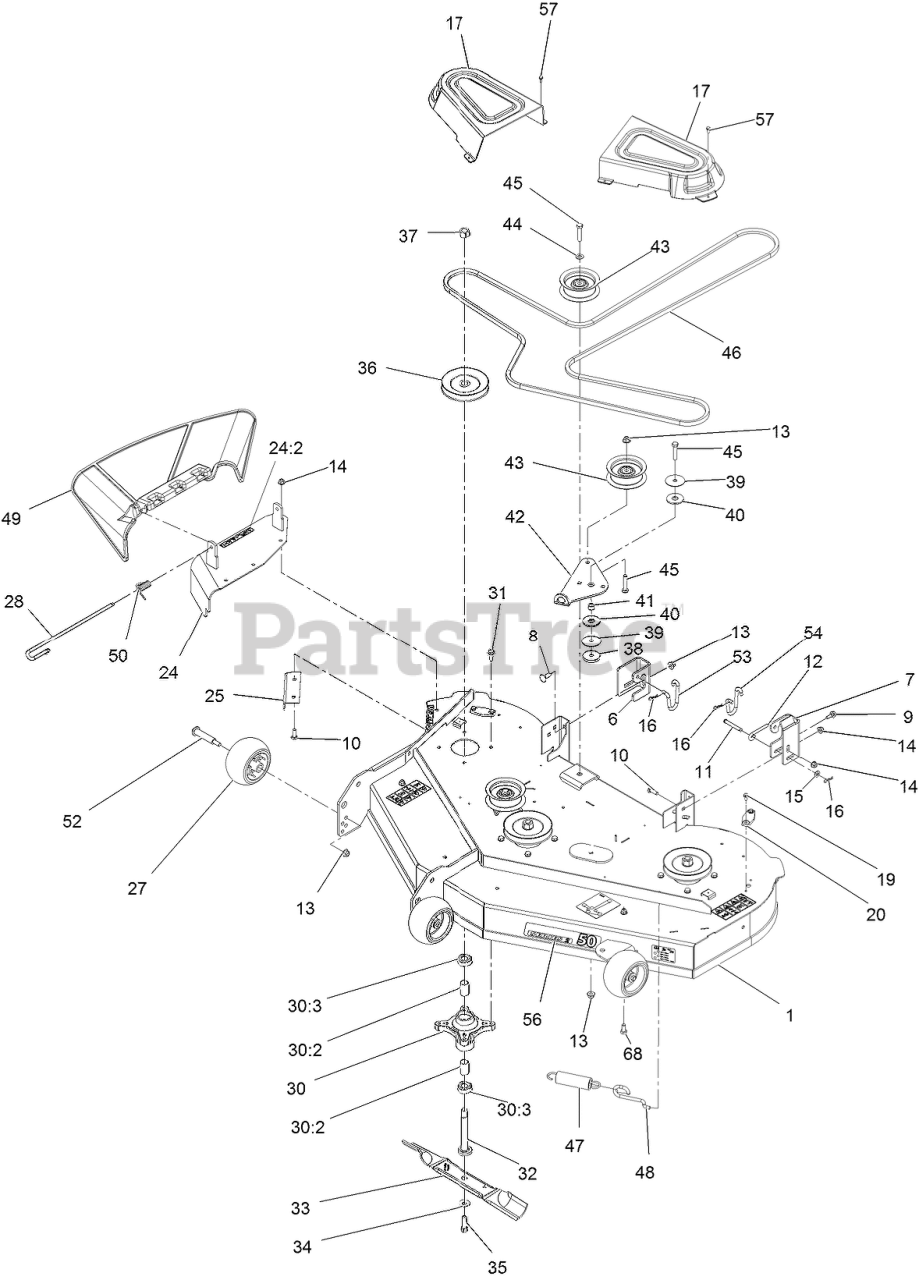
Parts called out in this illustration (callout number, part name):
1	DECK-50 W/DECALS
6	Bracket-Hanger, Right Rear
7	BRACKET-HANGER, LH
8	BOLT-CARR
9	SCREW-SHOULDER,HWH
10	SCREW-CARR
11	PIN-CLEVIS
12	Rod-Level, Deck
13	NUT-HF, NI
14	NUT-HF, NI
15	WASHER-PLAIN
16	PIN-COTTER
17	COVER-BELT
19	SCREW-HWH
20	COVER-WASHOUT PORT
24	COVER ASM W/DECAL
24:2	DECAL-DANGER
25	BAFFLE-CUTOFF
27	ROLLER-SCALP, ANTI
28	PIN-CHUTE
30	SPINDLE ASM
30:3	BEARING-BALL
31	SCREW-TAPTITE
32	SHAFT-SPINDLE
33	BLADE-HI LIFT
34	WASHER-BELLEVILLE
35	SCREW-HH
37	NUT-HEX
38	WASHER-PLAIN
40	WASHER-FRICTION, COMPOSIT
42	Arm-Idler
43	PULLEY-IDLER, FLAT
44	WASHER-FLAT
45	SCREW-HH
46	V-BELT
47	SPRING-EXTENSION
48	Hook-Return Spring
49	DEFLECTOR-DISCHARGE
50	SPRING-TORSION
52	BOLT-SHOULDER
53	LINK-RETENTION, DECK (RH)
54	LINK-RETENTION, DECK (LH)
56	Decal-50 Series 2
57	SCREW-TAPTITE
68	SCREW-HH
